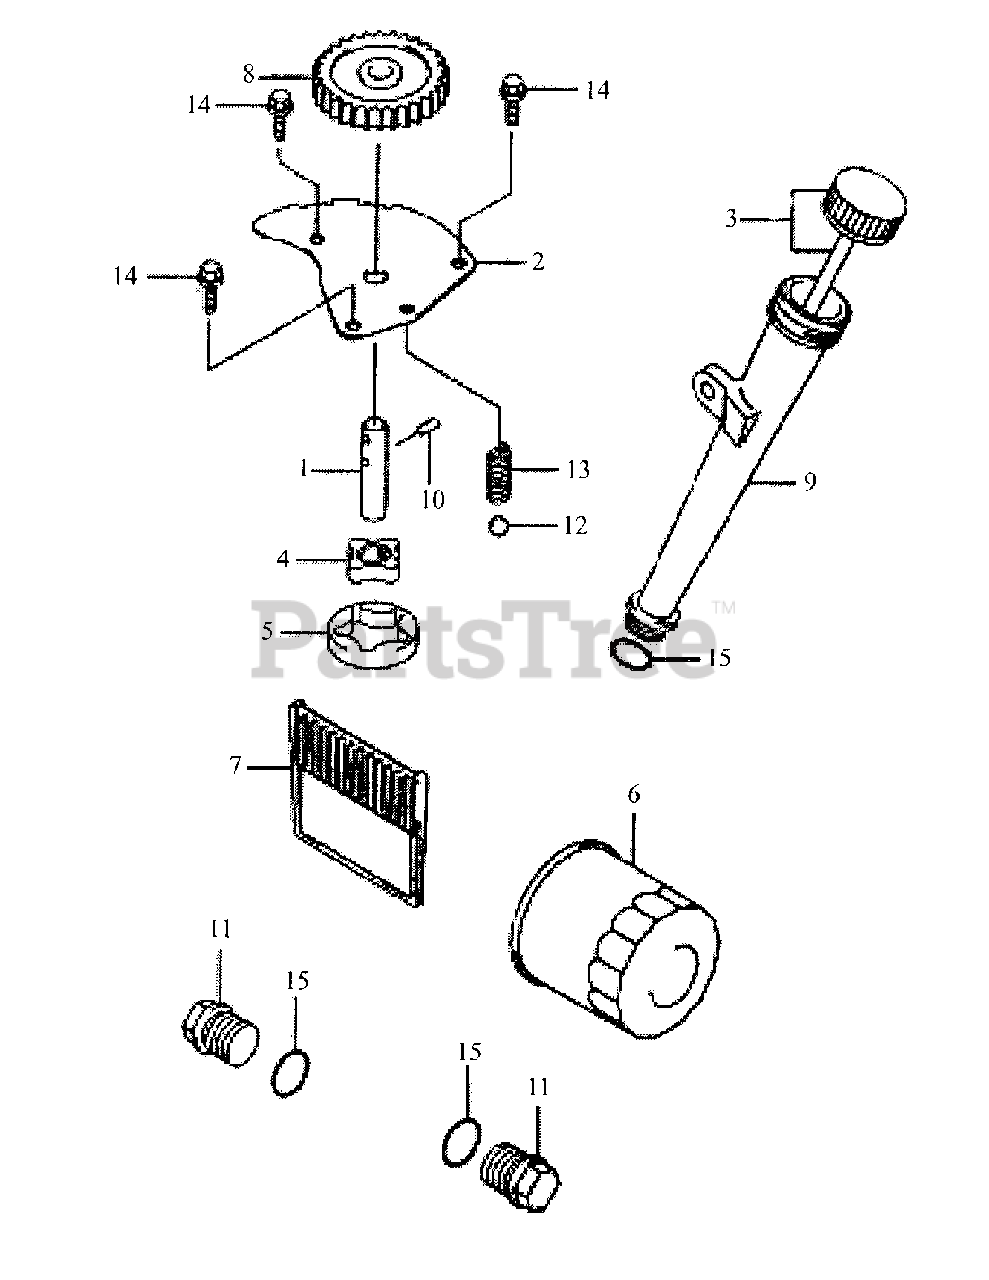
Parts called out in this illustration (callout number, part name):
1	Shaft, Oil Pump
3	Cap Assembly
4	Rotor, Pump In
5	Rotor, Pump Out
6	Filter, Oil
7	Filter Screen, Oil
8	Gear, Spur
9	Filler Tube
10	Pin
11	Plug
14	Bolt, Flange
